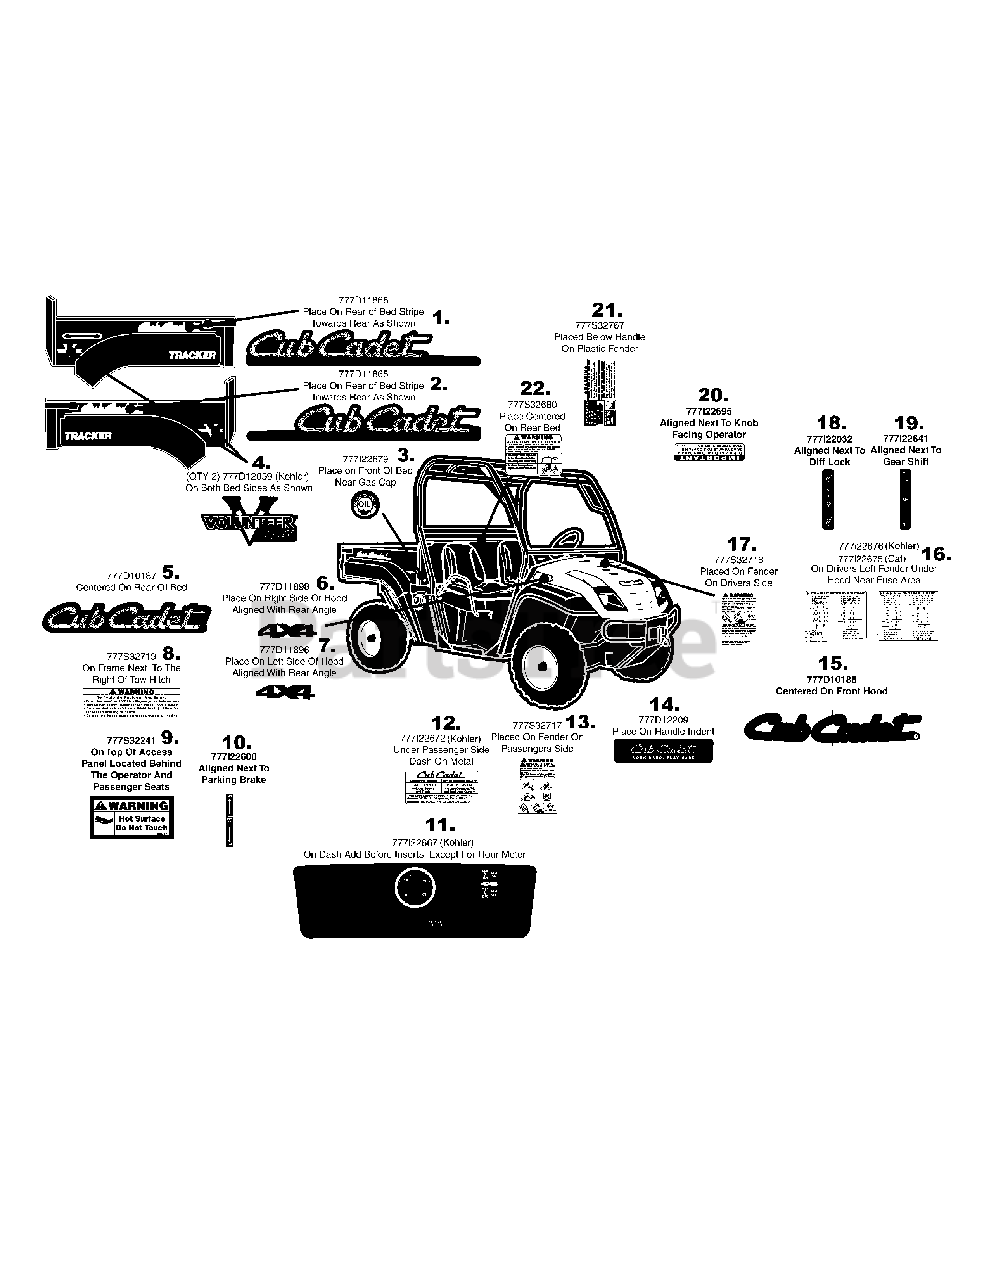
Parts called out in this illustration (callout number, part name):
1	LABEL-UV CUB CAMO EURO LEFT
2	LABEL-UV CUB CAMO EURO RIGHT
3	LABEL-CHECK ENG OIL
4	LABEL-UV VOL CAMO 624
5	LABEL-CUB CADET BED
6	LABEL-CUB UV 4X4 HOOD RH CAMO
7	LABEL-CUB UV 4X4 HOOD LH CAMO
8	LABEL-TOW HITCH
9	LABEL-HOT SURFACE
10	LABEL-PARK BRAKE
11	LABEL-DASH
12	LABEL-OPERATING WGT
13	LABEL-RIDER FALL RH FENDER
14	LABEL-UV DASH LOGO CAMO
15	LABEL-CUB CADET HOOD
16	LABEL:UV:4X4 KOHLER FUSE
17	LABEL-ROLL & FALL LH FENDER
18	LABEL-DIFF LOCK CO
19	LABEL-GEAR SHIFT
20	LABEL:4X4 SHIFT
21	LABEL-4X4 CARGO BOX HANDLE
22	LABEL-CARGO LOAD
